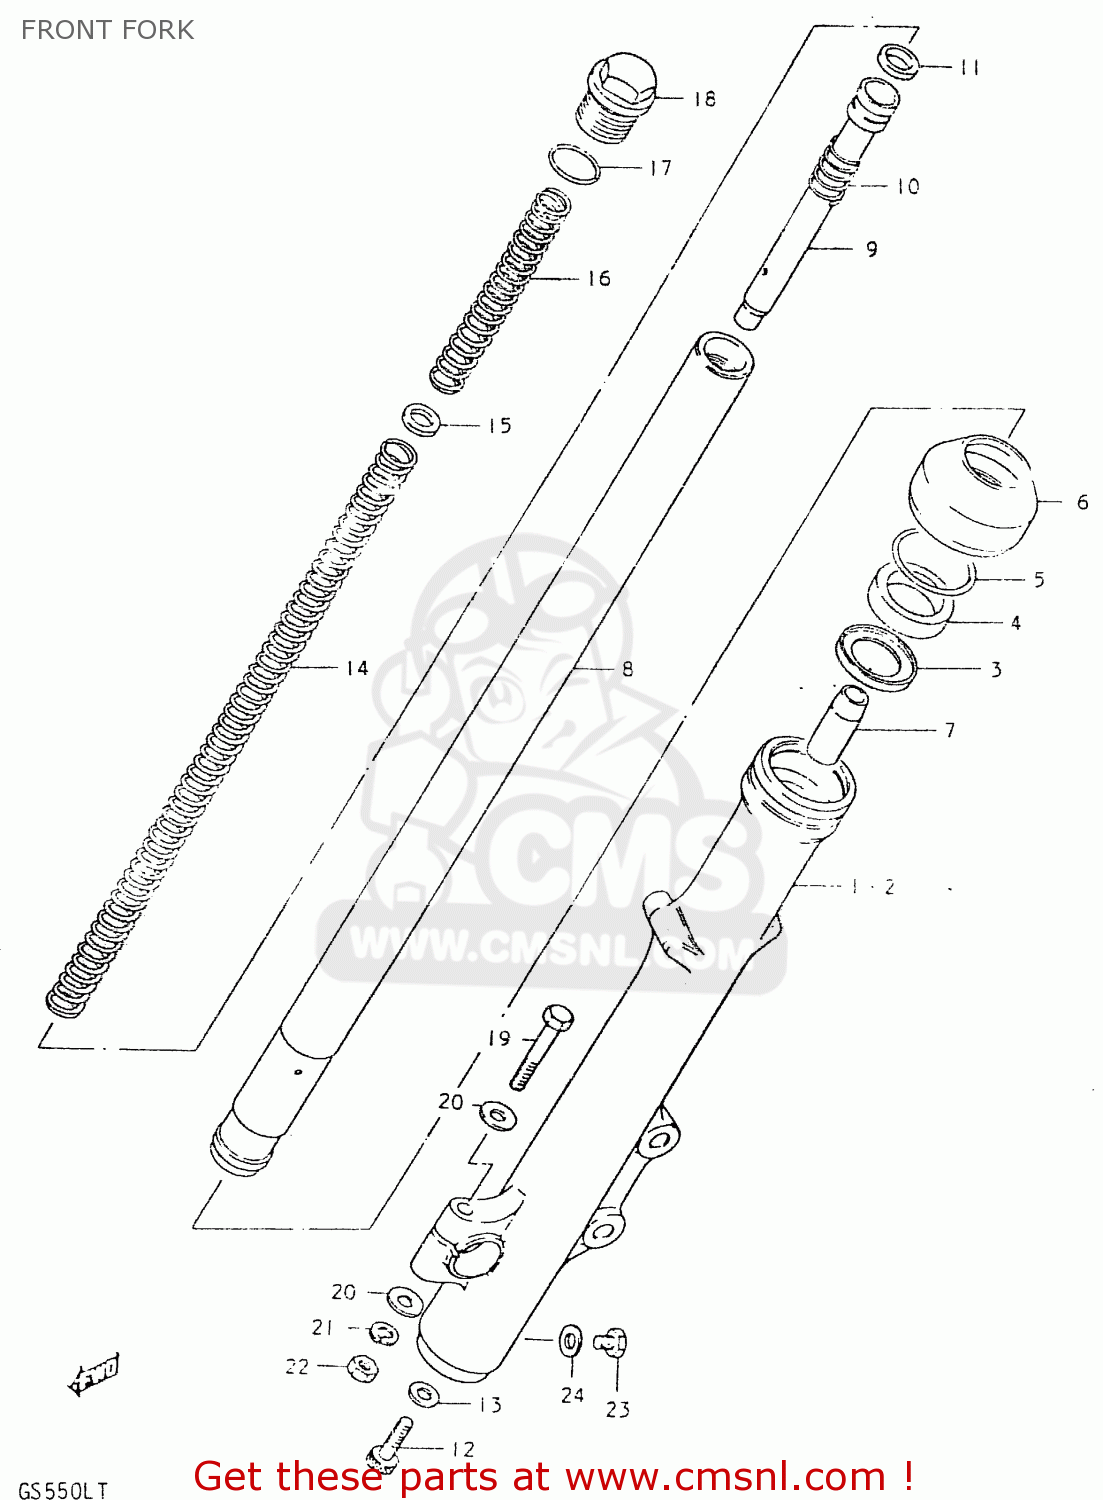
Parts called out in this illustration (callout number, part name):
1	OUTER TUBE, RH
2	OUTER TUBE, LH
3	SPACER,SEAL
4	OIL SEAL,FRONT FORK
5	CIRCLIP,FORK OIL SEAL
6	BOOT
7	PIECE,OIL LOCK
8	TUBE,FORK,INNER
9	CYLINDER,FRONT FORK
10	SPRING,FORK REBOUND
11	RING
12	BOLT(8X27)
13	GASKET (NAS)
14	SPRING,FRONT FORK MAIN,LOWER
15	WASHER,SPRING
16	SPRING,FRONT FORK,UPPER
17	O-RING
18	CAP,INNER TUBE
19	BOLT 8X50
20	WASHER
21	LOCK WASHER
22	NUT
23	BOLT
24	GASKET,DRAIN,PLUG (NAS)
